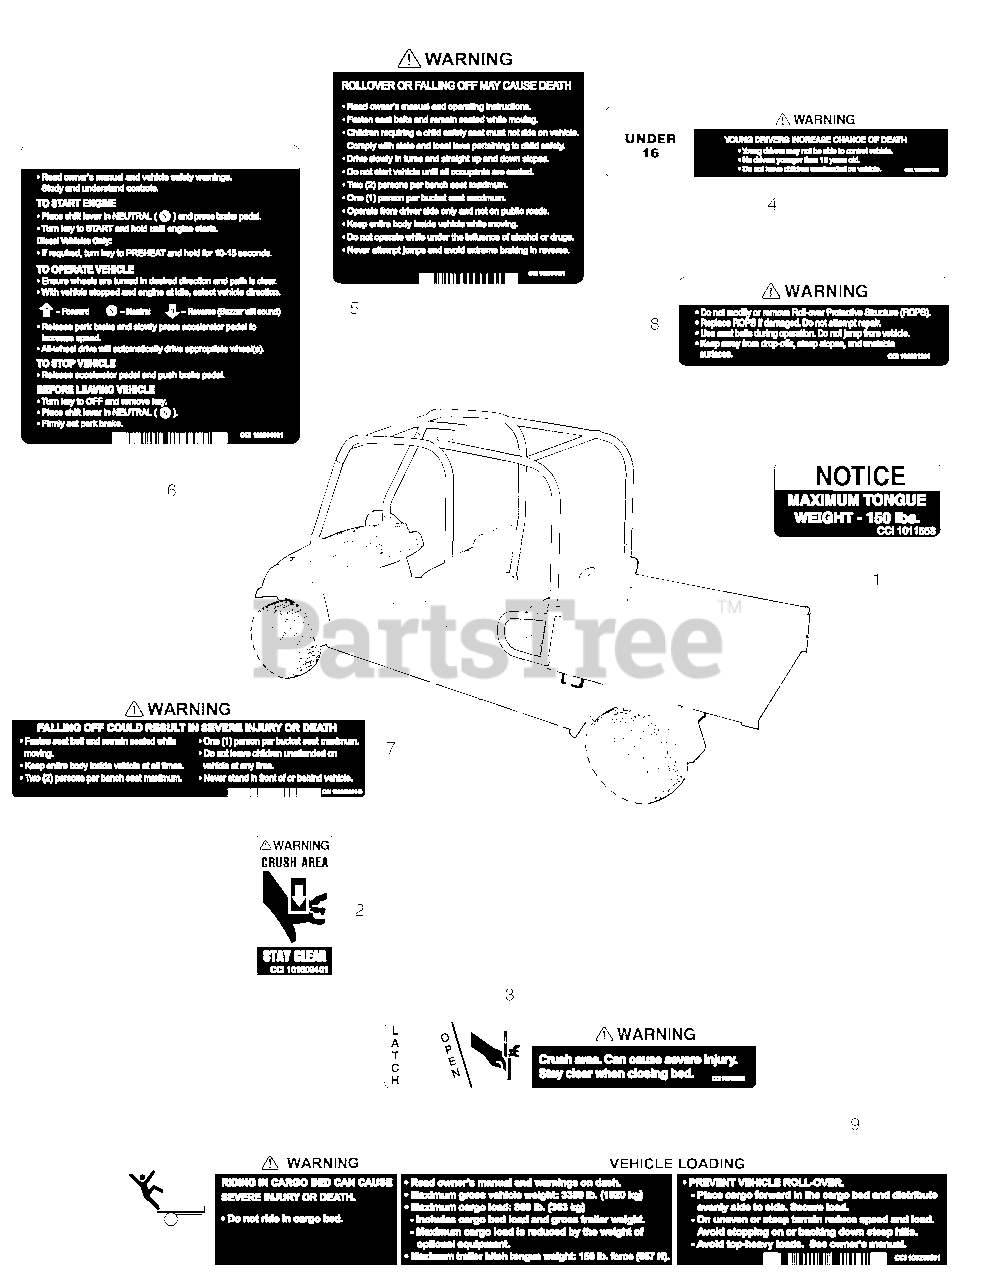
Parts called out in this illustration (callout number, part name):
1	Decal, Trailer Hitch
2	Decal, Crush Area Warning
3	Decal, Bed Crush Area Warning
4	Decal, Young Driver Warning
5	Decal, Operating Instr, AWD
6	Decal, Operator Warning
7	Decal, Warning, Passenger
8	Decal, Warning, AWD ROPS
9	Decal, Load, Vehicle, 3350 Lbs
